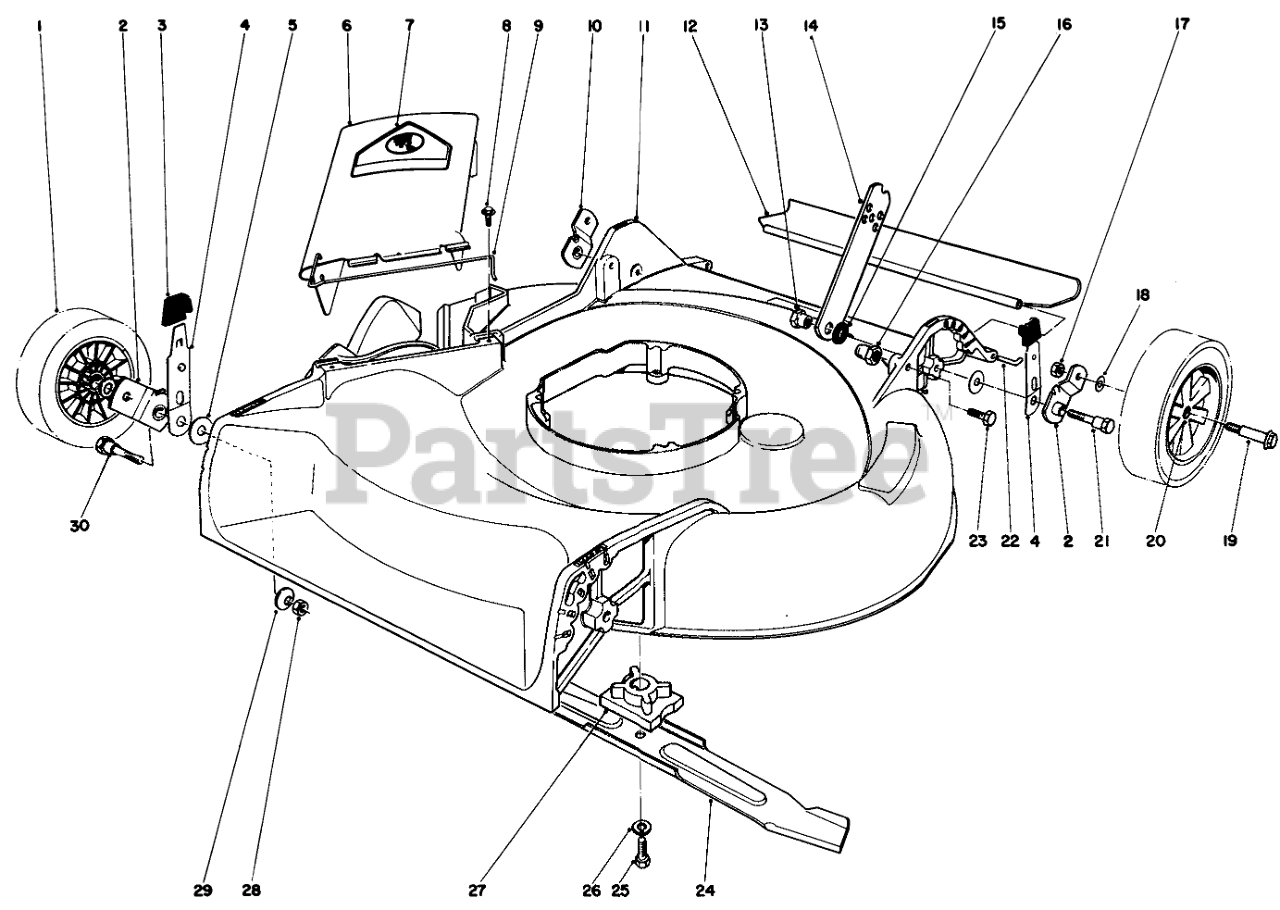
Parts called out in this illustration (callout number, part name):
1	Wheel & Tire Assembly (Incl. Ref. #20)
2	Pivot Arm
3	KNOB-ARM
4	SPRING ARM ASM
5	WASHER-PIVOT
6	Deflector Assembly (Incl. Ref. #7 8 9)
7	DECAL-DANGER
8	SCREW-HWH
9	SPRING HINGE
10	Pivot Arm
11	HOUSING/DECAL
12	REAR SAFETY SHIELD 21
13	HANDLE PIVOT NUT
14	HANDLE LATCH
15	SPACER
16	HANDLE PIVOT NUT
17	NUT-LOCK
17	Nut
18	WASHER
19	WHEEL BOLT
19	BOLT-WHEEL
20	BUSHING
21	PIVOT SCREW
22	SHIELD ROD
23	SCREW-HH
24	Blade
25	SCREW-HH
26	WASHER-LOCK
27	BLADE RETAINER
28	NUT-LOCK, NI
29	WASHER-BELLEVILLE
30	PIVOT SCREW
30	5/16-18 PIVOT SCREW
